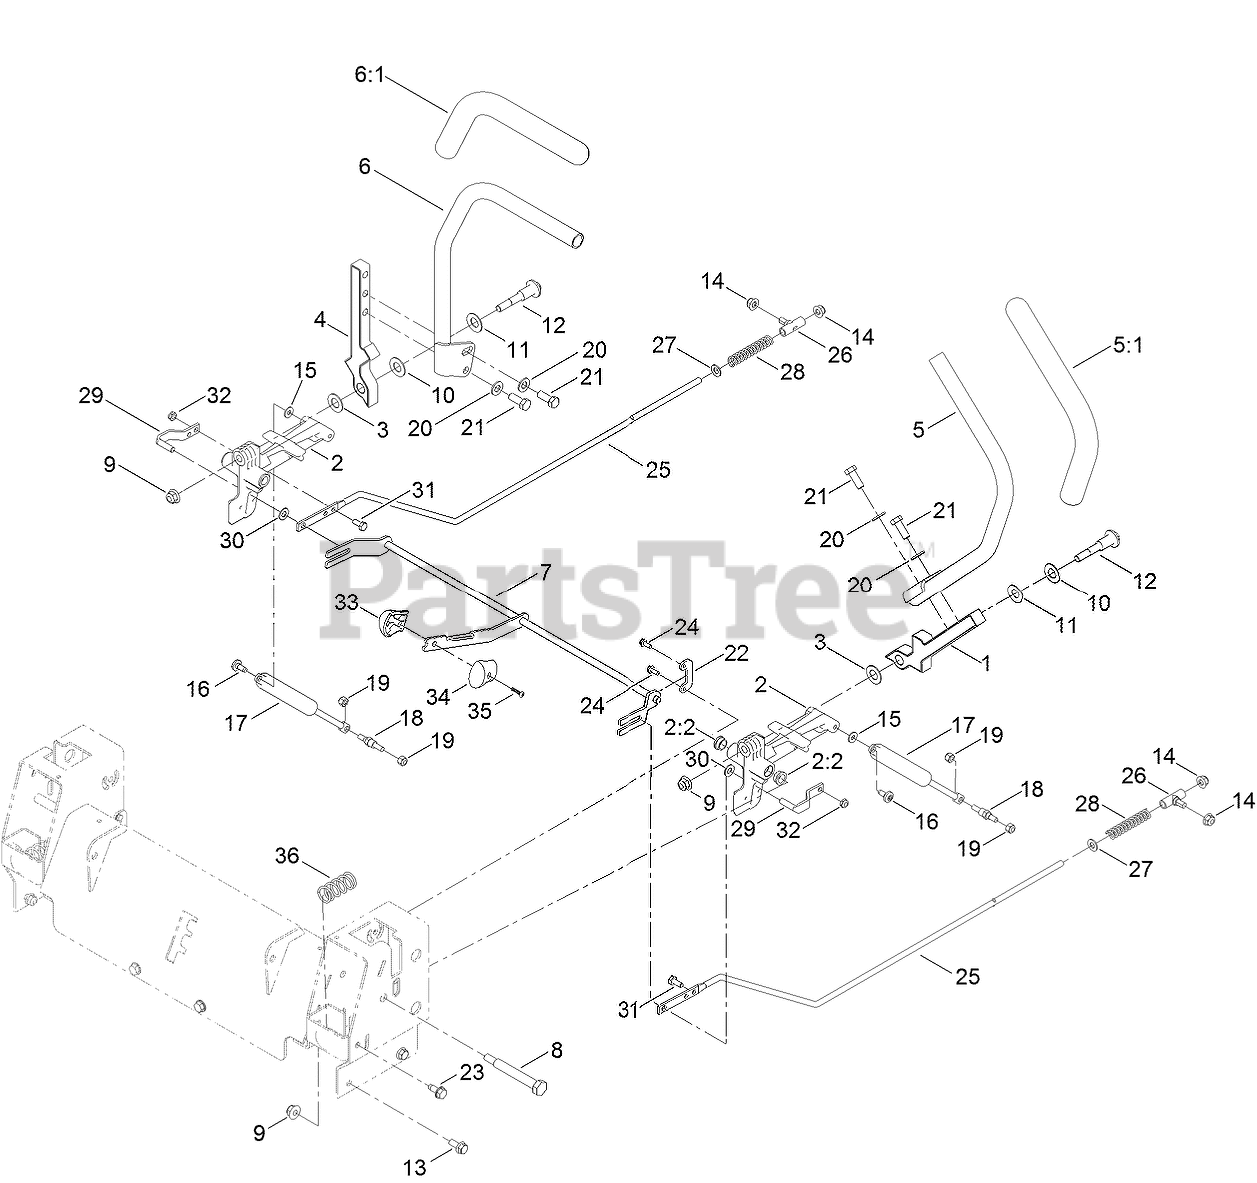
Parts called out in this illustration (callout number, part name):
1	CONTROL BOX ASM
2	ACTUATOR ARM ASM
2:2	BUSHING-FLANGE
3	WASHER-NYLON
4	ARM-CONTROL
5	HANDLE-CONTROL, LH
6	HANDLE-CONTROL, RH
7	SPEED CONTROL ASM
8	BOLT-PIVOT
9	NUT-HF, NI
10	WASHER
11	WASHER-BELLEVILLE
12	BOLT-PIVOT
13	SCREW-HHF
14	NUT-HF, NI
15	WASHER
16	SCREW-SHOULDER
17	DAMPER
18	STUD-DAMPER
19	NUT-LOCK, NI
20	WASHER-FLAT
21	SCREW-HH
22	RETAINER
23	SCREW-HWHTF
24	SCREW-TAPTITE
25	ROD-HYDRO
26	MOUNT-ROD, HYDRO
27	WASHER-PLAIN
28	SPRING-RETURN, NEUTRAL
29	PIN-ROD, HYDRO
30	SPACER-NYLON
31	SCREW-HH
32	NUT-LOCK, NI
33	KNOB-RH
34	KNOB-LH
35	SCREW-PPH
36	SPRING-RETURN
